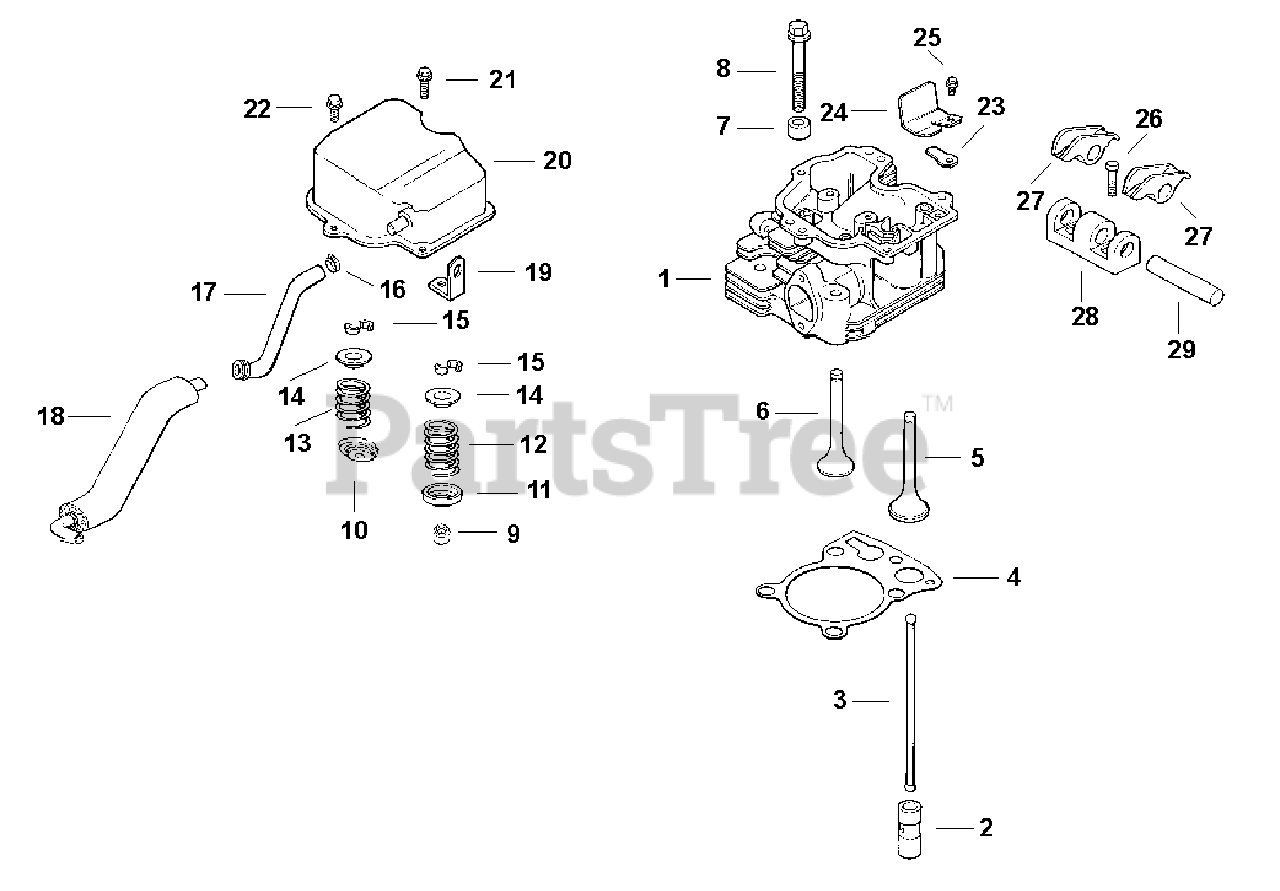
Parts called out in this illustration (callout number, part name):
1	KIT - USE 12 755 51
2	LIFTER - USE 12 351 02
4	GASKET, CYLINDER HEAD
5	VALVE, INTAKE
5	VALVE, INTAKE (.25 MM)
6	VALVE, EXHAUST
6	VALVE, EXHAUST (.25 MM)
7	KIT - USE 12 755 22
8	SCREW - USE 12 086 15
9	SEAL - USE 24 032 05
11	RETAINER, SPRING
13	SPRING
14	RETAINER, VALVE SPRING - USE 25 173 28-S
15	KIT, RETAINER
16	CLAMP, HOSE 1/2" USE 25 237 14-S
17	HOSE, BREATHER - USE 12 326 25-S
20	COVER - USE 12 096 07
21	SCREW - USE M-645025
22	SCREW - USE M-645020
23	REED - USE 12 402 02
24	RETAINER, REED
25	SCREW - USE M-545010
26	USE SM-642025-S
27	ARM - DISCONTINUED
29	SHAFT - (#DSC)
